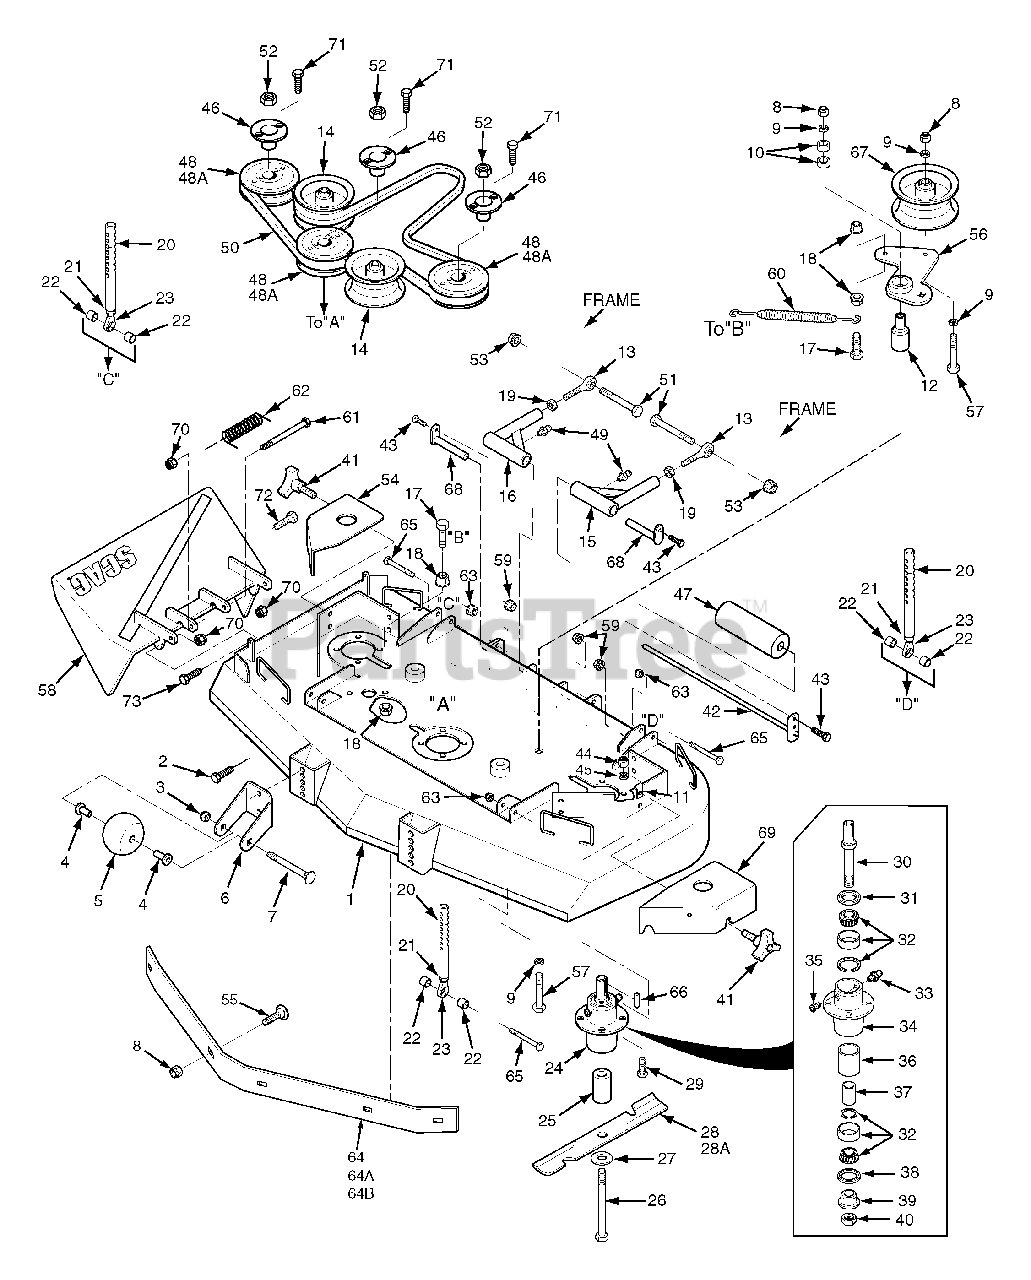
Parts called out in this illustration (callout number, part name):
1	Cutter Deck W/ Decals
2	Capscrew, 3/8-16 x 1" Serr. Flng.
3	Lock Nut, 3/8-16 Center Lock
4	Bushing, .376" ID Oilite
5	Wheel, Anti-Scalp
6	Bracket, Anti-Scalp Wheel
7	Bolt, Carriage 3/8-16 x 4"
8	Hex Nut, 3/8-16 Elastic Stop
9	Flatwasher, 3/8" (.938 x .391 x .105)
10	Ball Bearings
11	U-Nut, 3/8-16
12	Pivot, Idler
13	Rod End, Male 1/2-20 RH Thread
14	Pulley, Idler
15	Push Arm - LH
16	Push Arm - RH
17	Capscrew, Hex Head 3/8-16 x 1-1/2"
18	Nut, 3/8-16 Serrated Flange
19	Nut, 1/2-20 Jam
20	Pin Assembly
21	Nut, 3/8-24 Jam
22	Spacer, Deck Adjustment Pin
23	Rod End, Male 3/8-24
24	Spindle Assembly
25	Spacer, Spindle
26	Bolt,Hex Head 5/8-11 x 9-1/2"
27	Flatwasher, 5/8 W
28	Cutter Blade 21"
28A	Cutter Blade 21" Hi Lift
29	Bolt, Hex Head 5/16-18 x 1-3/4" Gr 8
30	Spindle Shaft
31	Seal, Cutter Spindle - Top
32	Tapered Bearings (Two)
33	Grease Fitting
34	Spindle Housing
35	Relief Fitting, Cutter Spindle
36	Spacer Outside
37	Spacer, Inside
38	Seal, Cutter Spindle - Bottom
39	Spindle Bushing
40	Nut, Spindle
41	Wing Nut, 3/8-16
42	Roller Shaft (small frame)
43	Bolt, Hex Head 5/16-18 x 1"
44	Hex Nut, 5/16-18 Elastic Stop Gr. 8
45	Lock Washer 5/16"
46	Tapered Hub
47	Guide, Roller
48	Pulley, 5.75 O.D.
48A	Puley, 6.35 O.D.
49	Grease Fitting, 90 Degree
50	Belt, Deck Drive
51	Bolt, Hex Head 1/2-13 x 3"
52	Hex Nut, 5/8-11
53	Hex Nut, 1/2-13 Elastic Stop
54	Belt Cover, RH
55	Bolt, Carriage 3/8-16 x 1"
56	Idler Arm Weldment
57	Capscrew, Hex Head 3/8-16 x 3"
58	Discharge Chute
59	Nut, 5/16-18 Serrated Flange
60	Spring, Deck Idler
61	Bolt, Hex Head 5/16-18 x 4-1/4"
62	Spring, Chute Return
63	Nut, 3/8-16 Elastic Stop
64	Baffle Weldment 48A
64A	Baffle Weldment 52A
64B	Baffle Weldment 61A
65	Bolt, Hex Head 3/8-16 x 2-1/2"
66	Key, 1/4" x 1/4" x 2"
67	Pulley, Idler
68	Push Arm Shaft
69	Belt Cover LH
70	Hex Nut, 5/16-18 Elastic Stop
71	Bolt, Hex Head 1/4-20 x 1" Gr. 8
72	Bolt, Hex Head 5/16-18 x 1-1/2"
73	Bolt, Hex Head 5/16-18 x 1-3/4"
